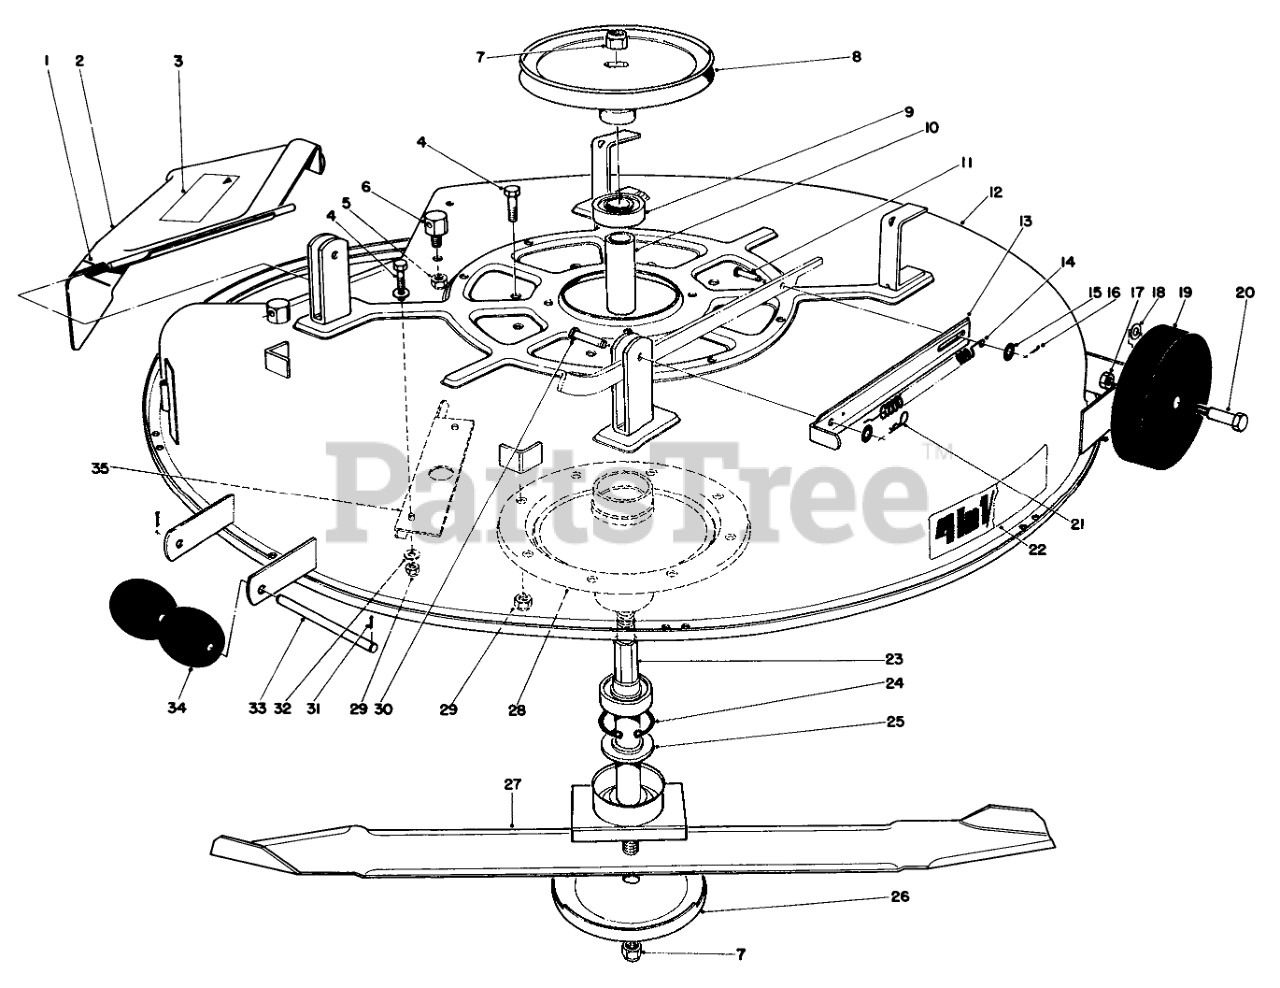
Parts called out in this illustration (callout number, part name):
1	SPRING
2	Deflector Assembly (Incl. Ref. #3)
3	Decal
4	SCREW-HH
5	NUT-LOCK, SIDE
6	POST-PIVOT
8	PULLEY(BLADE DRIVE)
9	BEARING-BALL
10	Spacer-Bearing
11	PIN-CLEVIS
13	DECK SPRING STRAP R
14	DECK TENSION SPRNG O
15	WASHER-FLAT
16	PIN-COTTER
17	Nut
18	WASHER-FLAT
19	DECK WHEEL
21	PIN-COTTER
22	DECK DECAL
23	SPINDLE SHAFT WA
24	RING-RETAINING
25	SPACER-SPINDLE
26	Cup
27	Blade
28	Spindle Body
29	NUT-LOCK, NI
30	PIN-CLEVIS
31	PIN-COTTER
32	WASHER-PLAIN
33	ROLLER SHAFT
34	ROLLER
35	Baffle Deck
